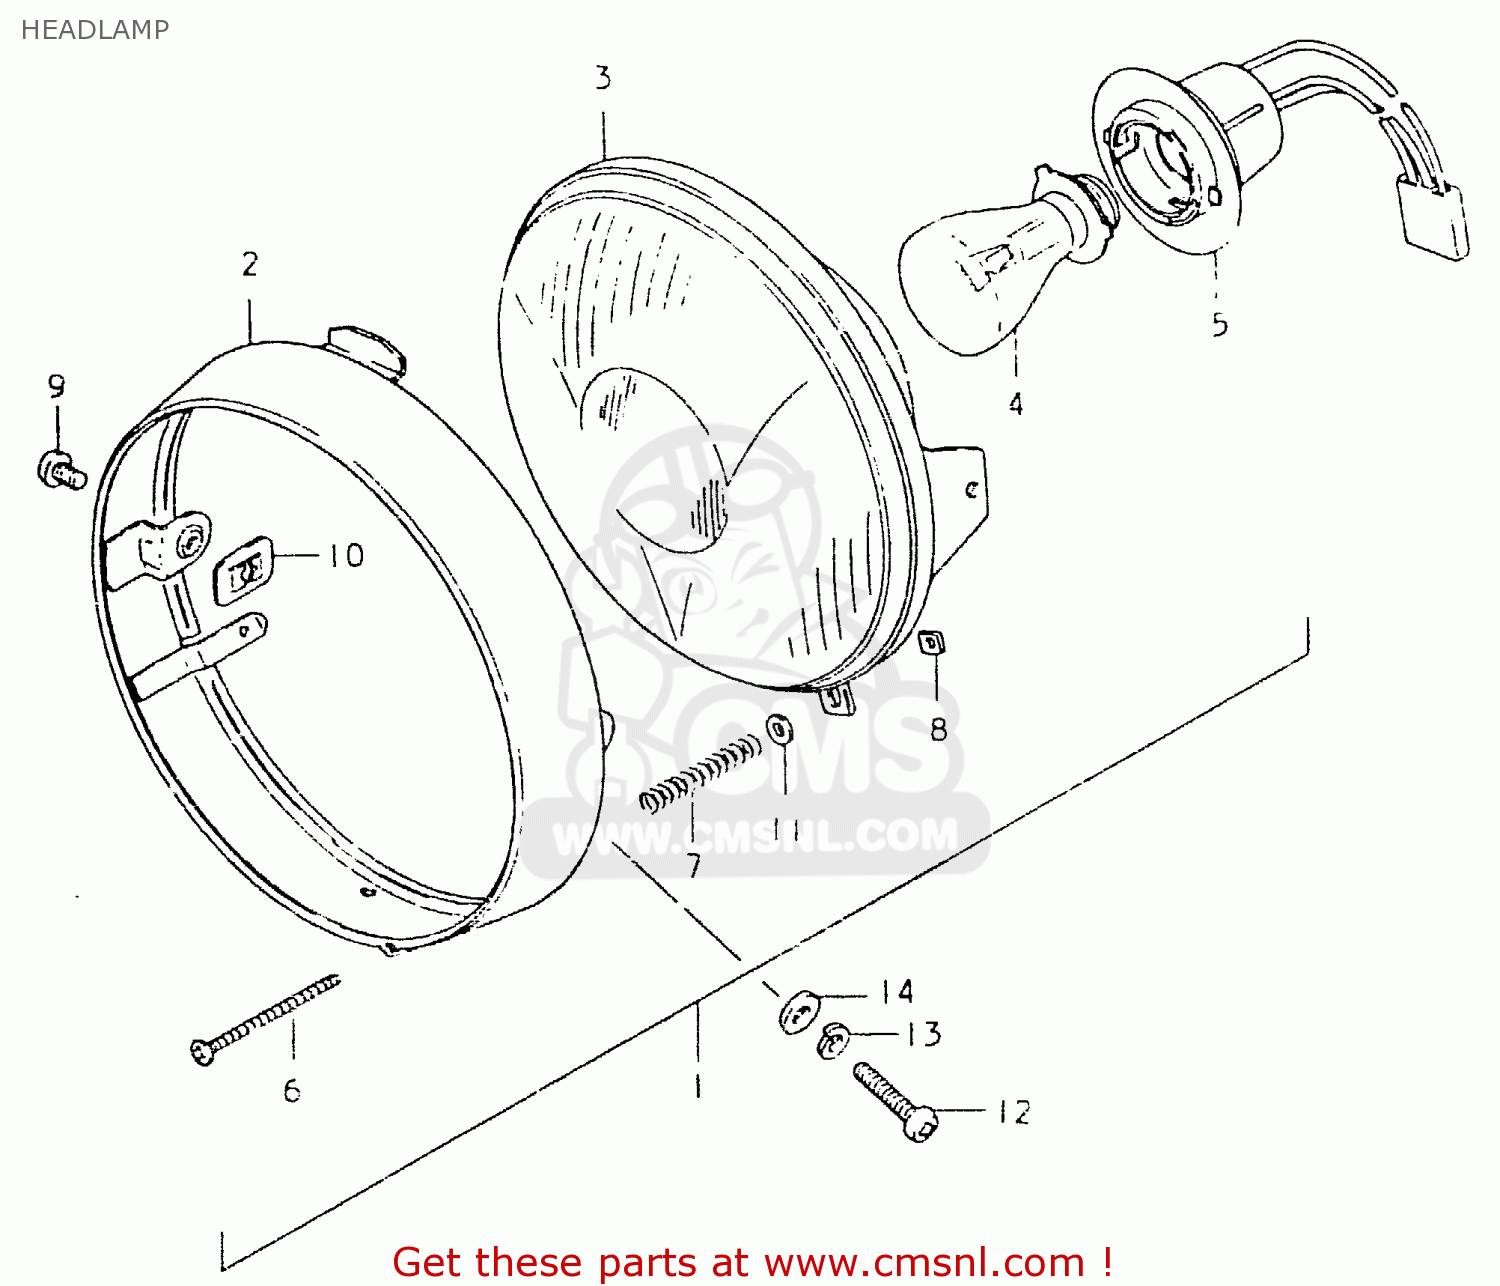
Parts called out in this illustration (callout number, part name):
1	HEADLAMP ASSY
2	RIM
3	LAMP UNIT
4	BULB(6V25/25W,STANLEY,A7007)
5	SOCKET,HEADLAMP
6	SCREW,HEADLAMP ADJUST
7	SPRING
8	NUT,HEADLAMP ADJUSTER
9	SCREW
10	NUT
11	WASHER
12	SCREW
13	LOCK WASHER
14	WASHER
